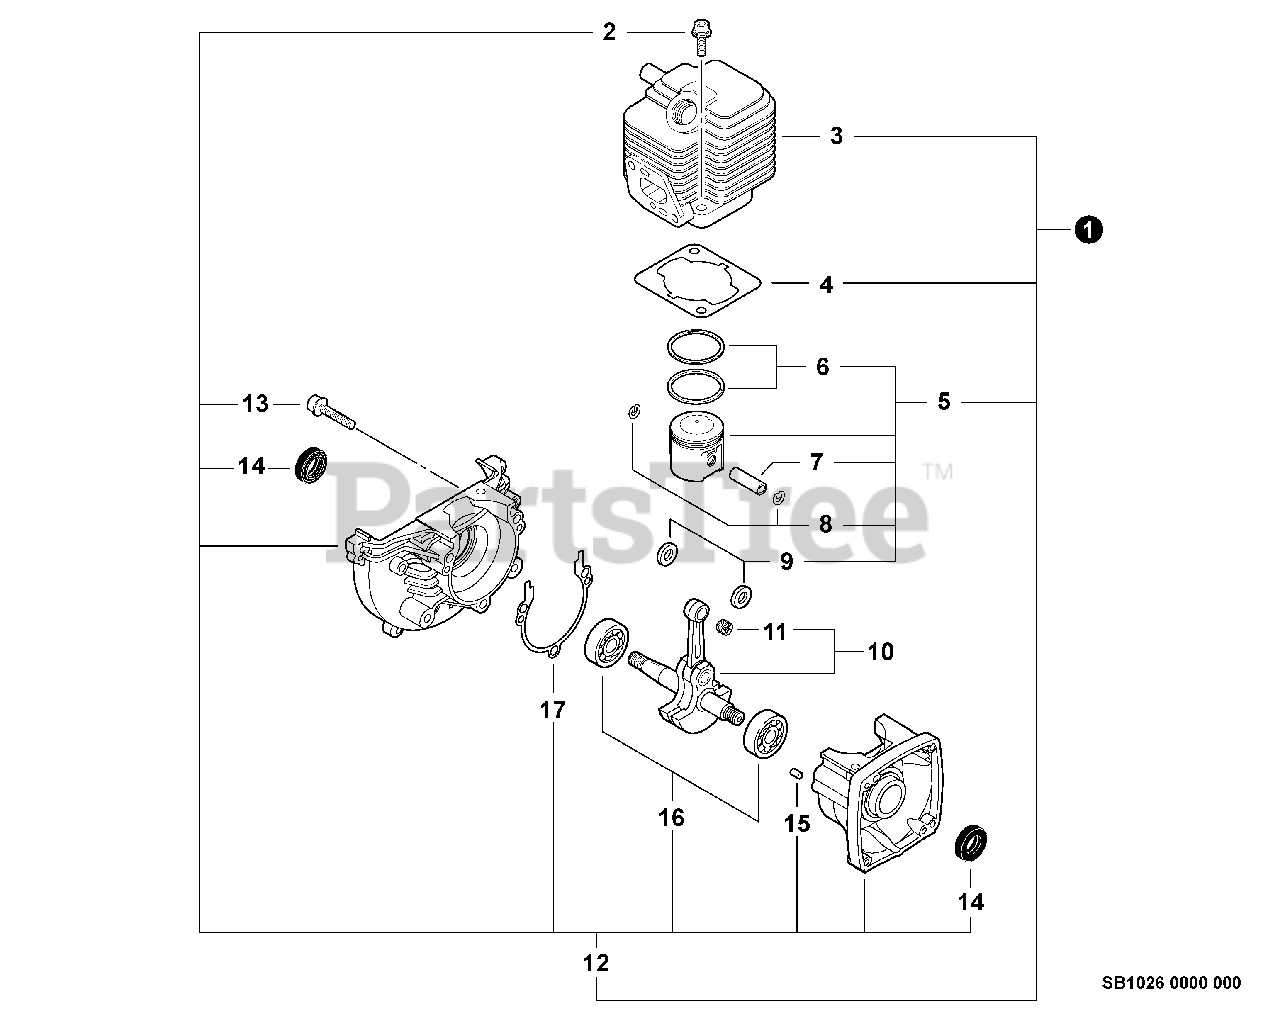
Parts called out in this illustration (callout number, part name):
1	SHORT BLOCK -- SB1026
2	SCREW - 5X22
3	CYLINDER
4	GASKET, CYLINDER
5	PISTON KIT
6	RING, PISTON
7	PIN, PISTON
8	RING, RETAINING
9	SPACER, PISTON
10	CRANKSHAFT ASSY
11	BEARING, NEEDLE - 8
12	CRANKCASE KIT
13	SCREW - 5X28
14	SEAL, OIL
15	PIN - LOCATING
16	BEARING, BALL - 6201
17	GASKET, CRANKCASE
